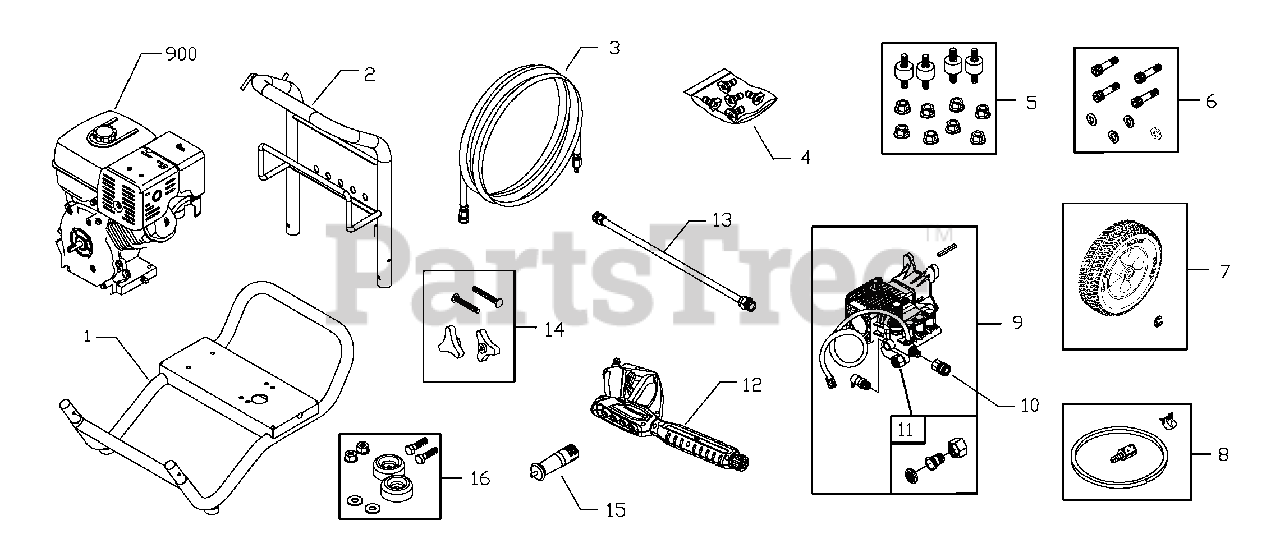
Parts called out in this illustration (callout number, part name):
2	HANDLE
4	KIT, QC Nozzles
5	KIT, Hardware, Engine Mounting
6	KIT, Hardware, Pump Mounting
9	PUMP
10	FITTING
11	ADAPTER, Garden Hose
13	EXTENSION, QC
14	KIT, Hardware, Handle
16	MOUNT, Vibration
900	* ENGINE
